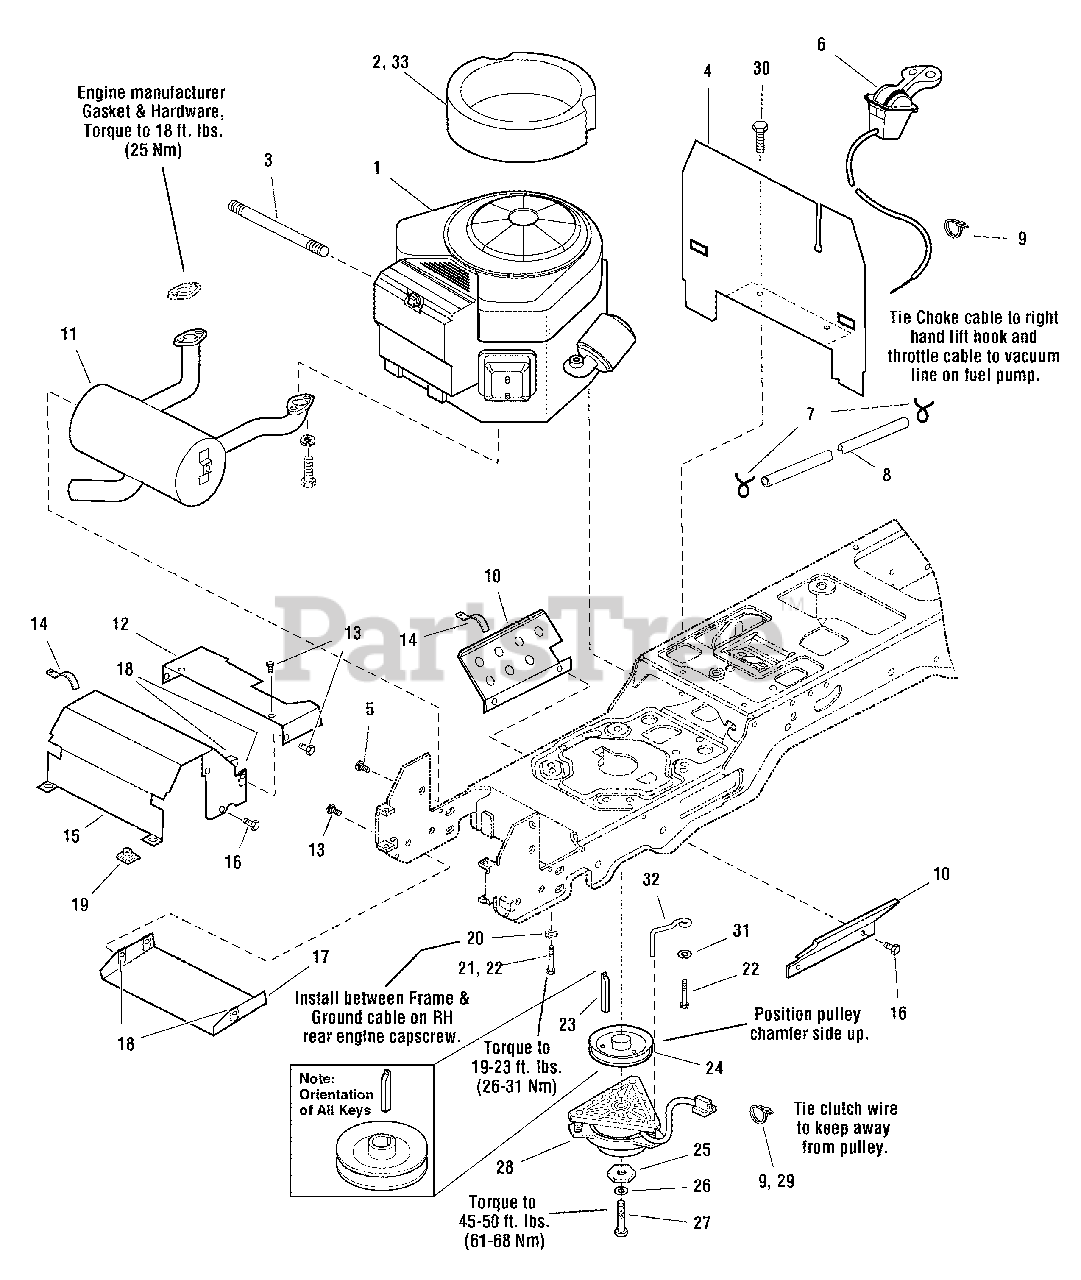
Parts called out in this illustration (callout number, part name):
2	SEAL, Foam
3	HOSE, Oil Drain
5	CAPSCREW, Hex Washer Head Taptite 5/16-18 x 1/2
6	CONTROL, Throttle Double 39.0 LG w/Knobs
6	THROTTLE, Control Double 51.0 LG w/Knobs
7	CLAMP, Hose
9	TIE, Self Locking
10	SHIELD, Side
11	MUFFLER, Kohler Twin
12	DUCT, Muffler
13	CAPSCREW, Hex Whiz Lock Flange 1/4-20 x 5/8
14	CLIP, Speed Wire
15	DUCT, Muffler Top
16	SCREW, Hex Washer Head Taptite 1/4-20 x 3/8
17	SHIELD, Muffler
18	NUT, Speed 1/4-20 Lug Type
19	NUT, Speed 5/16-18 Lug Type
20	LOCKWASHER, External Tooth 3/8
21	CAPSCREW, Hex Washer Head Taptite 3/8-16 x 1
22	CAPSCREW, Hex Washer Head Taptite 3/8-16 x 1-1/2
23	KEY, Hi-Pro
24	PULLEY & HUB ASMY
25	WASHER, Hex
26	LOCKWASHER, Spring
27	CAPSCREW, Hex Head 7/16-20 x 3-1/2 G5
28	CLUTCH, Electric
29	TIE, Self Locking
30	CAPSCREW, Hex Washer Head Taptite 1/4-20 x 1/2
31	WASHER, 3/8
32	RETAINER, Clutch
33	EDGING, Rubber
